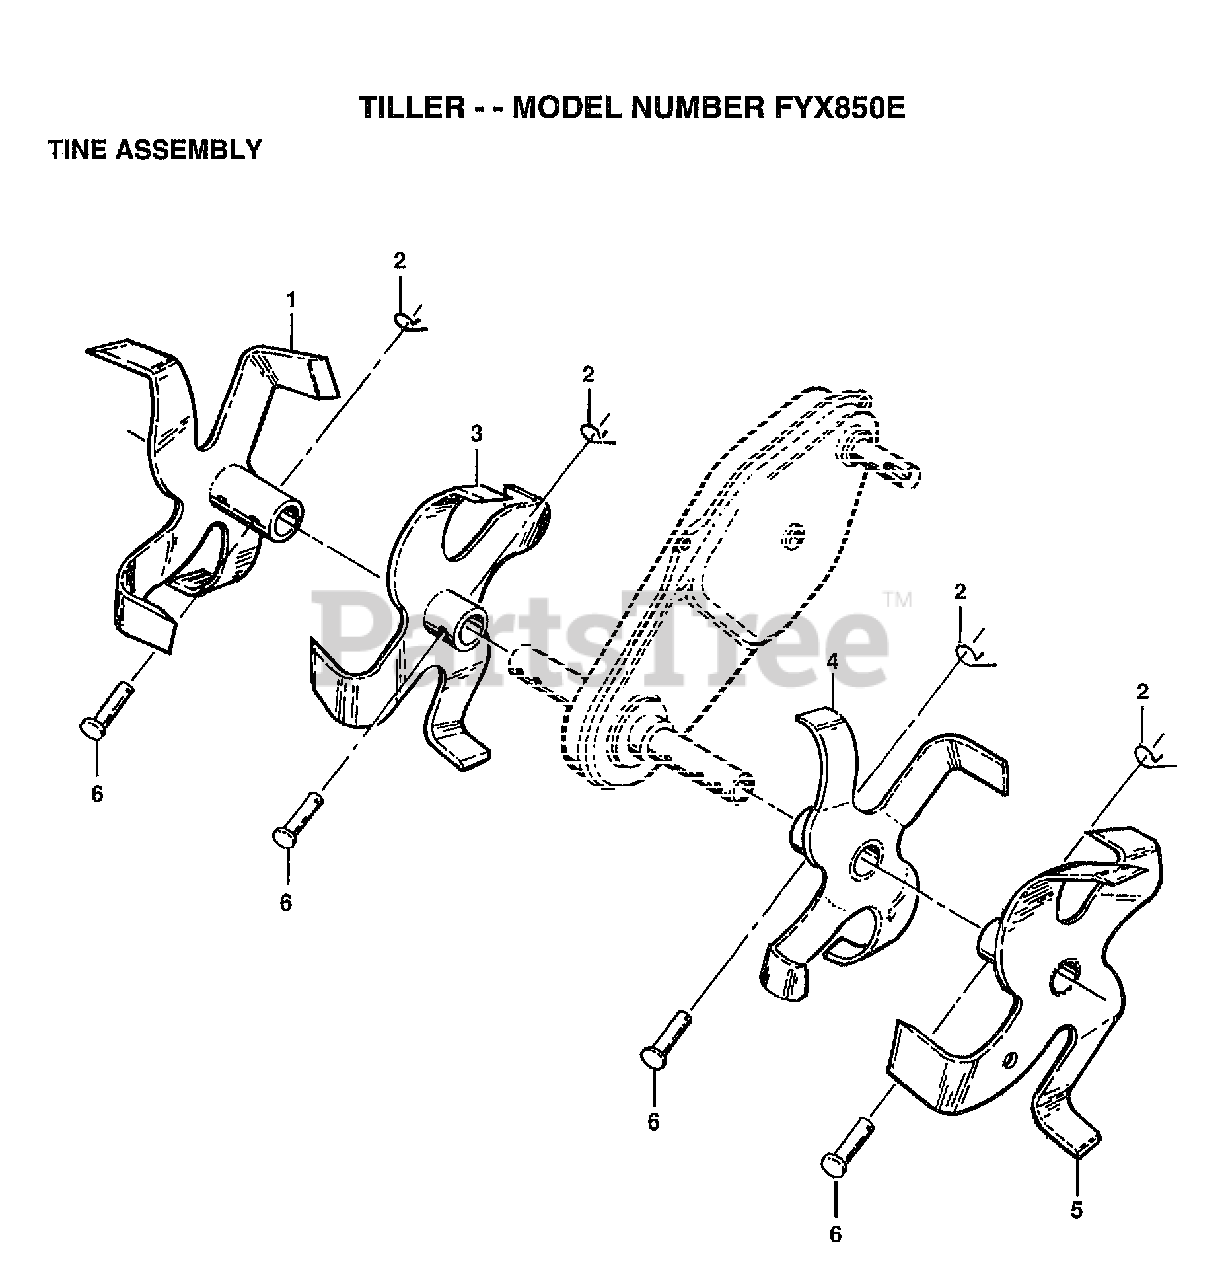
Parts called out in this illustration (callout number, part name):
1	"TINE ASM OUTER,RH"
2	RETAINER SPRING
3	"TINE ASM INNER,RH"
4	TINE ASM INNER LH
5	"TINE ASM OUTER,LH"
6	RIVET.PAN HD.1.75
